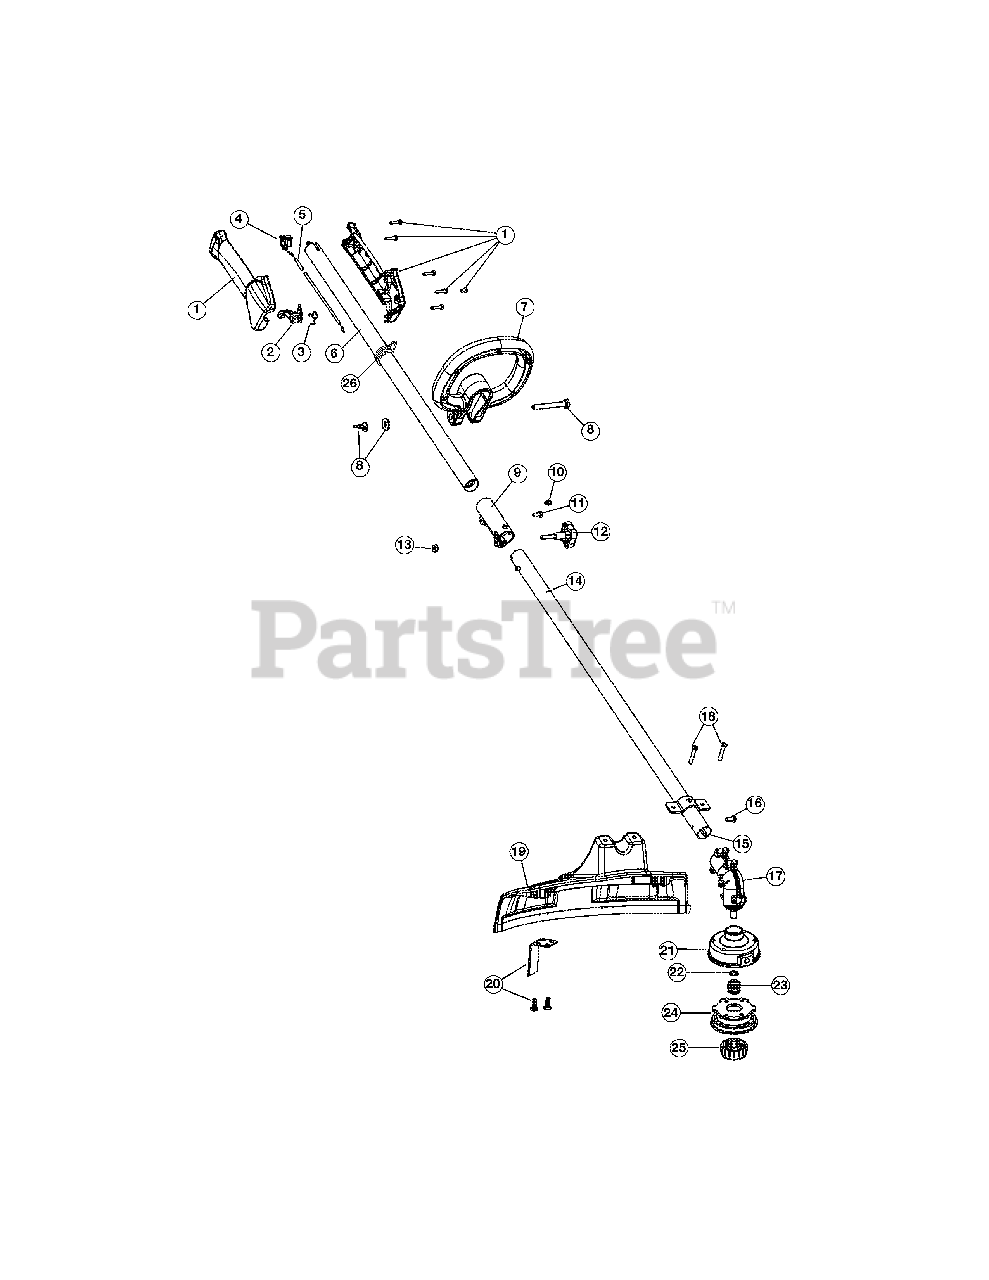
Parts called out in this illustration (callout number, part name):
1	Throttle Housing Assembly (includes 2-4)
2	Throttle Trigger
3	Throttle Trigger Spring
5	Throttle Cable Assembly
6	Upper Drive Shaft Housing Assembly
7	D-Handle Assembly (includes 8)
8	Handle Hardware
9	Split Boom Coupler (includes 10-13)
12	Adjustment Knob (includes 13)
13	Knob Retaining Nut
14	Lower Drive Shaft Housing Assembly
15	Lower Flexible Drive Shaft
16	Anti-Rotation Screw
17	Gear Box Assembly (includes 16 & 21-25)
18	Shield Mounting Screws
19	Shield Assembly (includes 20)
20	Blade Assembly
21	Outer Spool Assembly (includes 22)
22	Retainer
24	Inner Reel
25	Bump Knob Assembly
26	Shoulder Strap Clip
